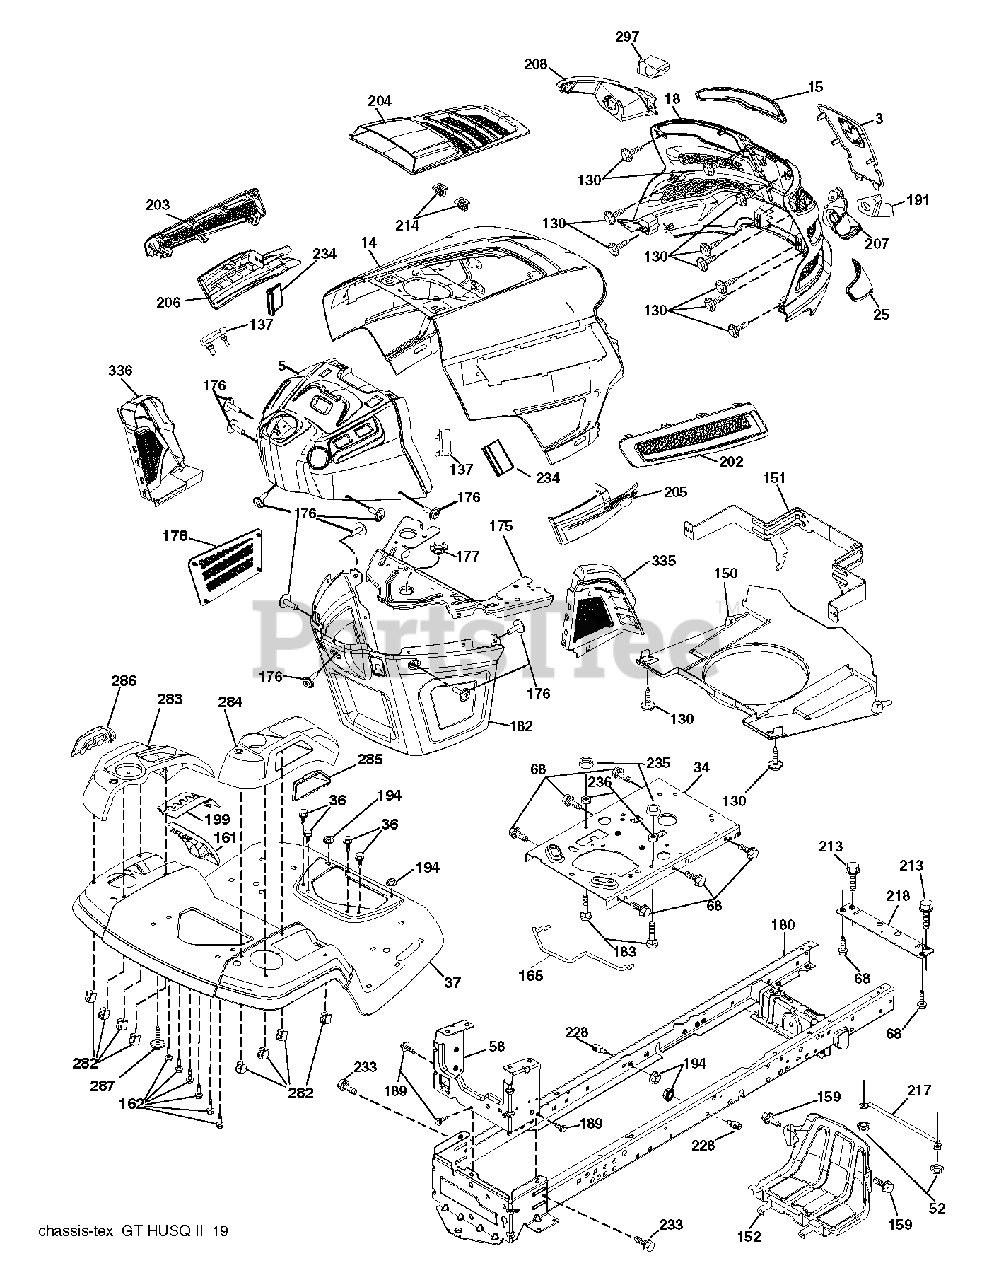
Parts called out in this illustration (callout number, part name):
3	APPLIQUE.SUBASM.GT.HUSQ.II
5	DASH.UPP.GT2.DUAL.RD.PTO.MCHOK
14	HOOD.ASM.HUSQVARNA.GT.TEX.422
15	LENS.HEADLIGHT.LH.GTII.2011
18	GRILLE.SUBASM.GT.HUSQ.II
25	LENS.HEADLIGHT.RH.GTII.2011
34	X-PIECE.HOOD.STOP.NON/
36	SCREW 5/16"
37	FENDER.TLT.FS.W/CPH/FW/RSF.ORN
52	LOCKNUT
58	DRAWBAR UPPER 2PC SMALL FENDER
68	SCREW LT
130	SCREW.#10 X 0.750.BOS
137	BUMPER DASH
150	AIR.DUCT.GTV.BLACK
151	BRACKET.PIVOT.HOOD.GT.HUSQ.II
152	SHIELD.BROWNING.PNT.GT.V2
159	SCREW, 3/8-16X3/4
161	WINDOW FUEL
162	SCREW.HI-LO.CONSOLE
165	SUPPORT.TANK.REAR.W/TEX
175	PLATE.CROSSMEMBER.HUSQ
176	SCREW.#10-24X5/8.RN.QU
177	BUSHING, STEERING
178	CARGO.ASM.NET.TXGT.W/C
180	CHASS.WLDMNT.TL.12GA/2P.48/54
182	DASH.LOWER.COMMON.12V.ADAPTOR
183	BOLT.5/16-18X1-1/4 FULL THD
189	SCREW
191	INSERT.REFLECTIVE.RH.HUSQ.GTII
194	NUT LOCK HEX FLANGE 5/16-18
199	PLATE.DECK.LIFT.HUSQ.LT
202	VENT.SIDE.RH.GT.HUSQ.II.
203	VENT.SIDE.LH.GT.HUSQ.II.498
204	VENT.TOP.HUSQ.GT2
205	SIDE.TRIM.RH.GT.HUSQ.II
206	SIDE.TRIM.LH.GT.HUSQ.II.GRAY
207	BEZEL LIGHT.RH.GT.II.MYLAR
208	BEZEL LIGHT.LH.GT.II.MYLAR
213	BOLT
214	CLIP.RETAINER.TINNER.
217	ROD.PIVOT.HOOD
218	X-PIECE.HOOD.STOP.NON/
228	STUD.FASTNER.W/ANTI-ROTATE
233	BOLT.SHOULDER
234	BUMPER.HOOD.TEX.HUSQVARNA
235	SPACER FENDER
236	NUT.CENTERLOCK.5/16-
282	CLIP.RETAINER.CONSOLE.LT.HUSQ
283	CONSOLE.DECK.LFT.R.SDFL.HUSQLT
284	CONSOLE.CNTRL.
285	CONSOLE INSERT RH
286	CONSOLE.INSRT.LH.HUSQ.LT.BLACK
287	SCREW 1/4X20
297	INSERT.REFLECTIVE.LH.HUSQ.GTII
335	COVER.RH.CLOSE.OUT.BLACK
336	COVER.LH.CLOSE.OUT
